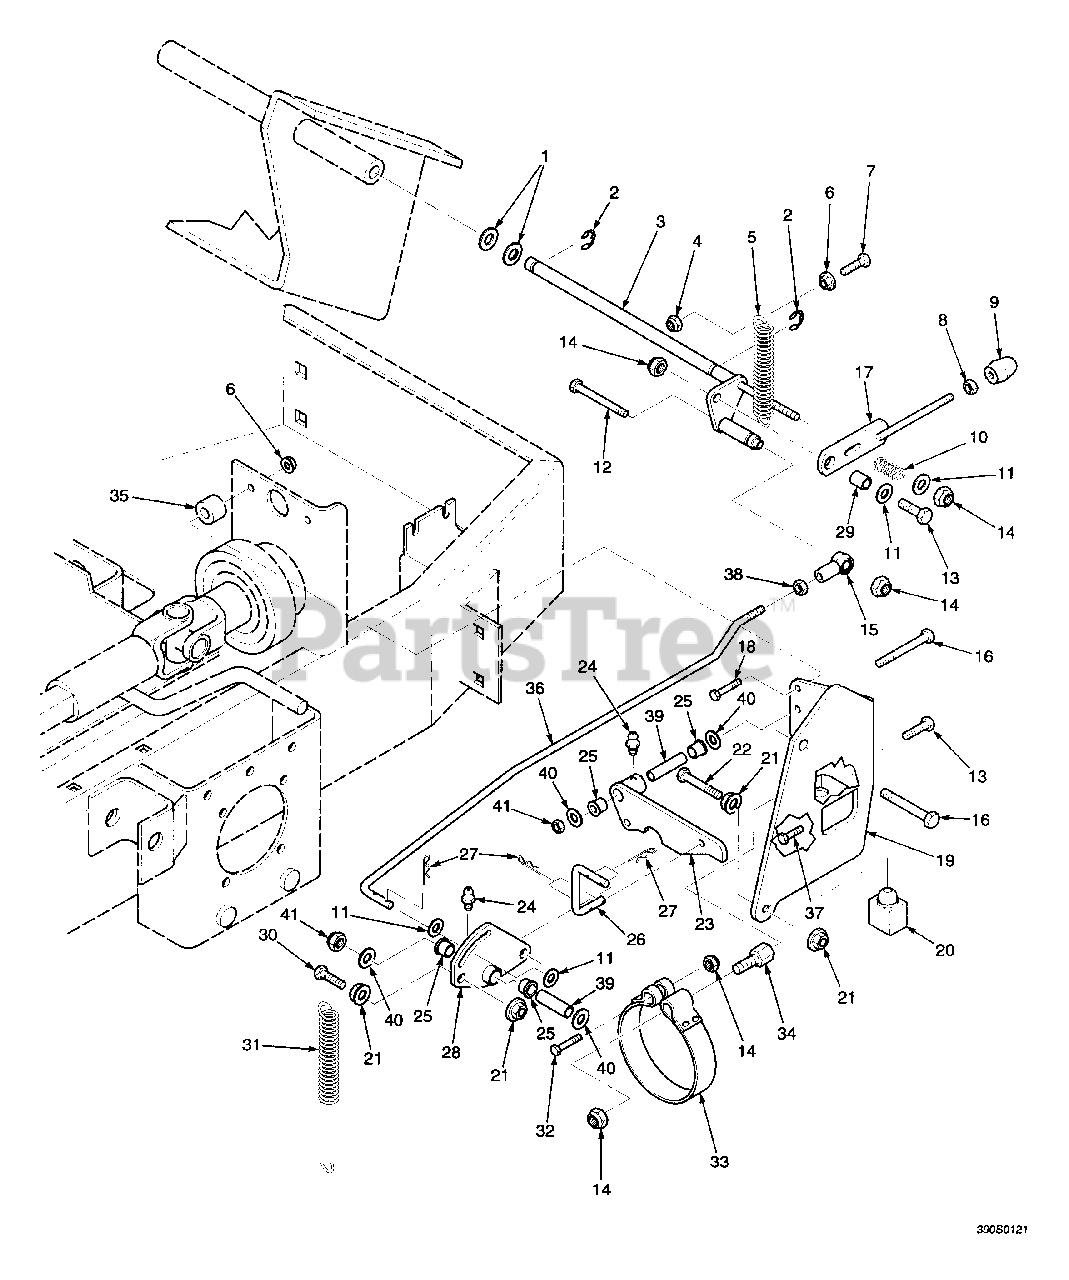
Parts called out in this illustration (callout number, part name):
1	Flatwasher, 3/4 (.766 x 1.250 x .060)
2	Retaining Ring - .75 Ext
3	Lever, Clutch Engage
4	Hex Locknut, Elastic Stop, 5/16-18
5	Spring, Clutch Lever
6	Serr. Fl. Hex Nut, 5/16-18
7	Serr. Fl. Hex Head Capscrew, 5/16-18 x 1
8	Nut, Hex, 3/8-16
9	Grip, Clutch Lever
10	Spring, Friction Control
11	Flatwasher, 3/8 (.391 x .938 x .105)
12	Bolt, Hex Head, 3/8-16 x 3-3/4
13	Serr. Fl. Hex Head Capscrew, 3/8-16 x 3/4
14	Hex Locknut, Elastic Stop, 3/8-16
15	Ball Joint, RH Thd, 3/8-16
16	Bolt, Hex Head, 5/16-18 x 2-1/2
17	Lever, Clutch
18	Serr. Fl. Hex Head Capscrew, 5/16-18 x 1-1/2
19	Base, Brake Assembly
20	Switch, Interlock
21	Serr. Fl. Hex Nut, 3/8-16
22	Bolt, Hex Head, 3/8-16 x 2-1/2
23	Lever, Brake Engage
24	Grease Fitting, Short
25	Bushing, Oilite - .50 I.D.
26	Rod, Clutch Engage
27	Cotter Pin, Hair (.080 x 1.19)
28	Bellcrank, Clutch Engage
29	Sleeve
30	Bolt, Hex Head, 3/8-16 x 1-1/2
31	Spring, Brake
32	Bolt, Hex Head, 3/8-16 x 1-1/4
33	Brake Band
34	Anchor, Brake
35	Spacer, Brake
36	Rod, Clutch Engage
37	Serr. Fl. Hex Head Capscrew, 5/16-18 x 1-3/4
38	Hex Nut, 3/8-24
39	Sleeve, Control Lever
40	Flatwasher, 5/16 (.344 x .688 x .065)
41	Hex Locknut, Elastic Stop, 5/16-18
